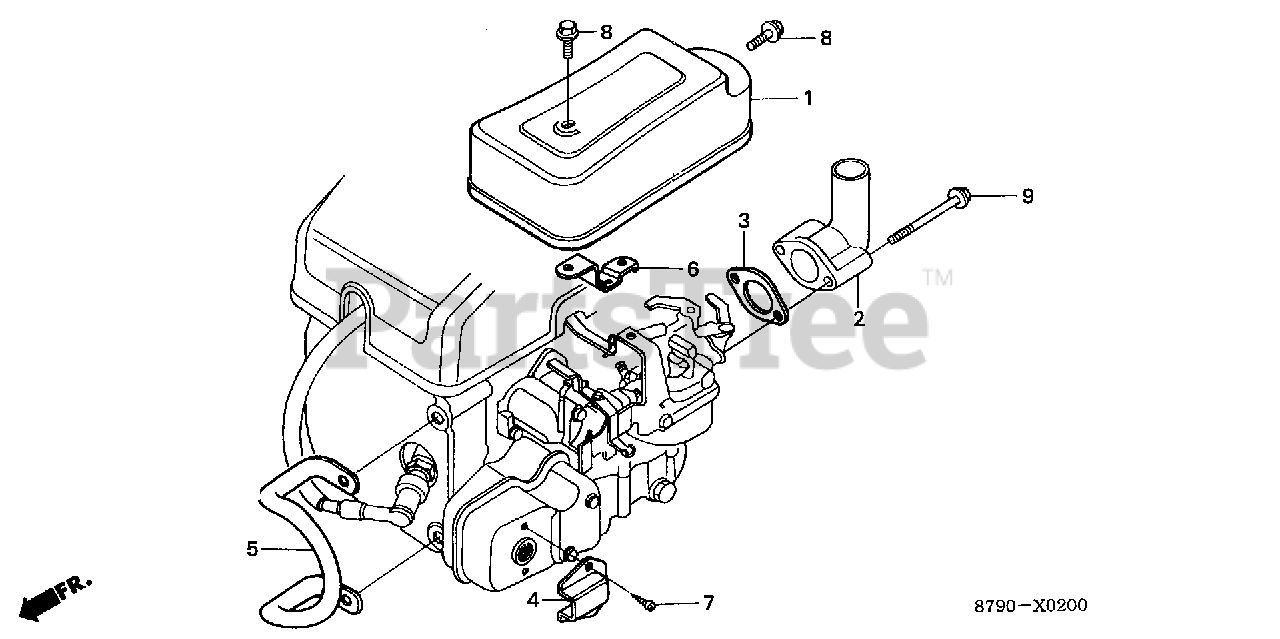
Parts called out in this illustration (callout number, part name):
1	COVER, CARBURETOR
2	ELBOW, AIR CLEANER
3	GASKET, AIR CLEANER ELBOW (NOT AVAILABLE)
4	DEFLECTOR, MUFFLER
5	GUARD, PLUG
6	STAY, ENGINE SWITCH
7	SCREW, TAPPING (5X8)
8	BOLT, FLANGE (6X12)
9	BOLT, FLANGE (6X50)
